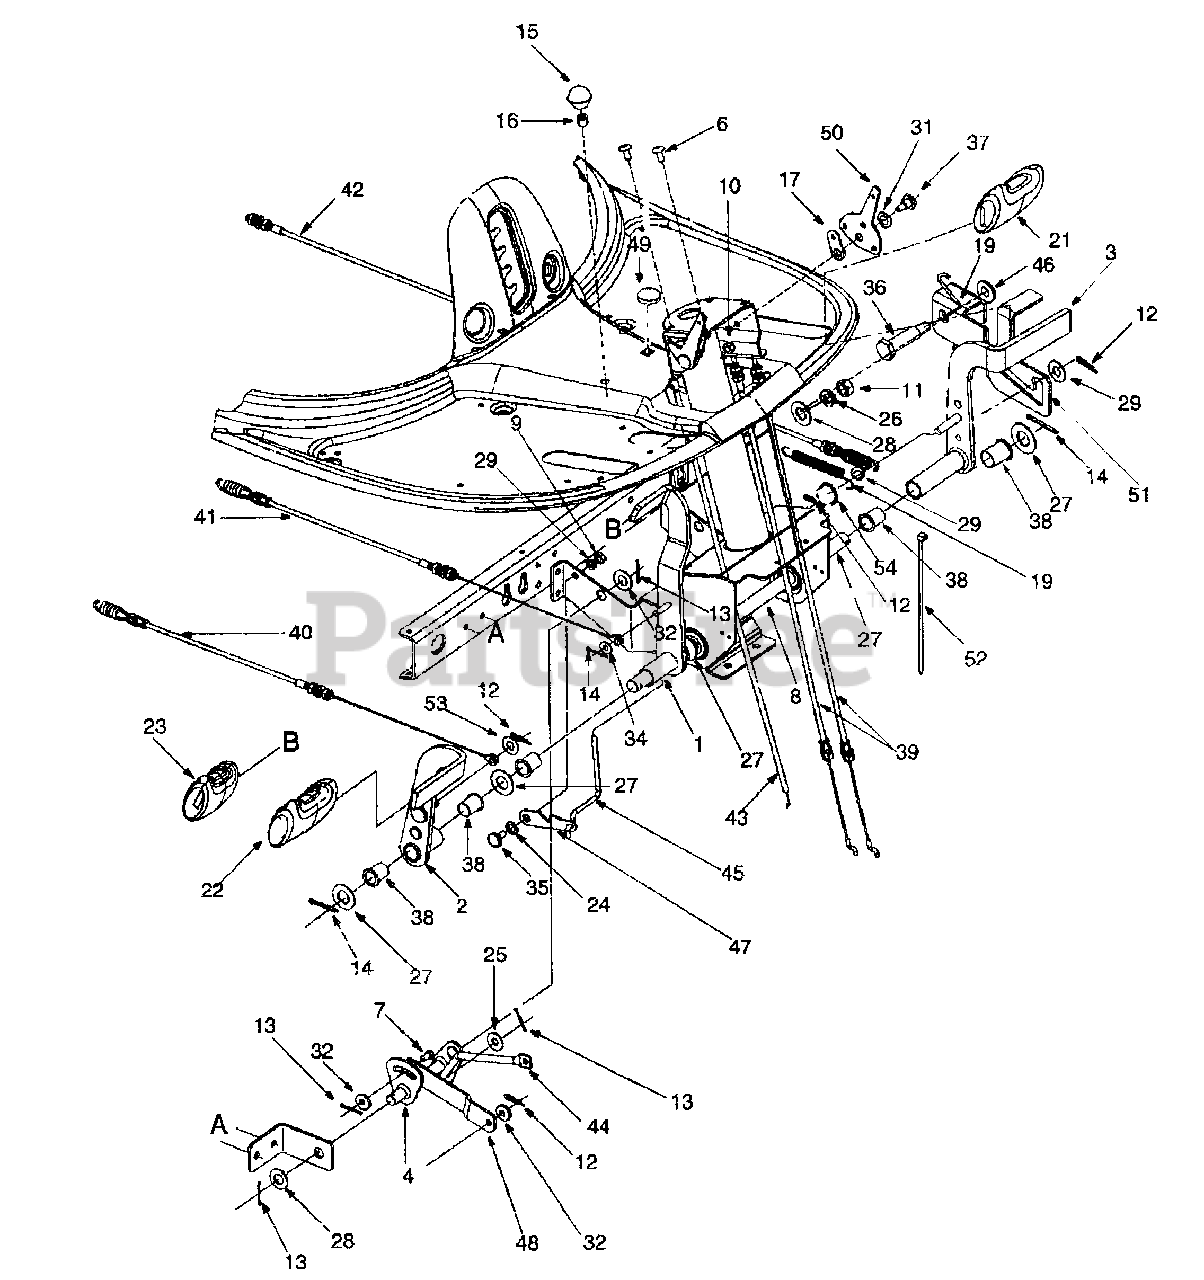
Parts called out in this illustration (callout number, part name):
7	Clevis Pin
9	Hex Nut 1/4-20
10	Lock Nut 1/4-20
11	Hex Nut 3/8-16
12	Internal Cotter Pin
13	Hairpin Clip
14	Hairpin Clip
15	Ball Knob
16	Snap-on Bushing
17	Stop Lever
19	Torsion Spring
22	Drive Pad
23	Brake Pad
24	Flat Washer 3/8 X .620 X .033
25	5/16 Washer
26	Lock Washer
27	Flat Washer
28	Flat Washer .510 X 1.00 X .060
29	Flat Washer .406 x 1.25 x .10
31	Spring Washer
32	Flat Washer
34	Flat Washer .271 X .630 X .065
35	Shoulder Screw .375 Dia X .18
36	Shoulder Screw
37	Shoulder Screw .375 X .380 X 1/4-20
38	Flange Bearing
39	Shift Cable
40	Variable Drive Cable
41	Brake Cable
42	Deck Cable
43	Throttle Choke Cable: 67"
44	Brake Rod
45	Brake Lock Out Rod
46	Shoulder Spacer
50	Shift Lever
53	Flat Washer.406 I.D. x.875 O.D.
